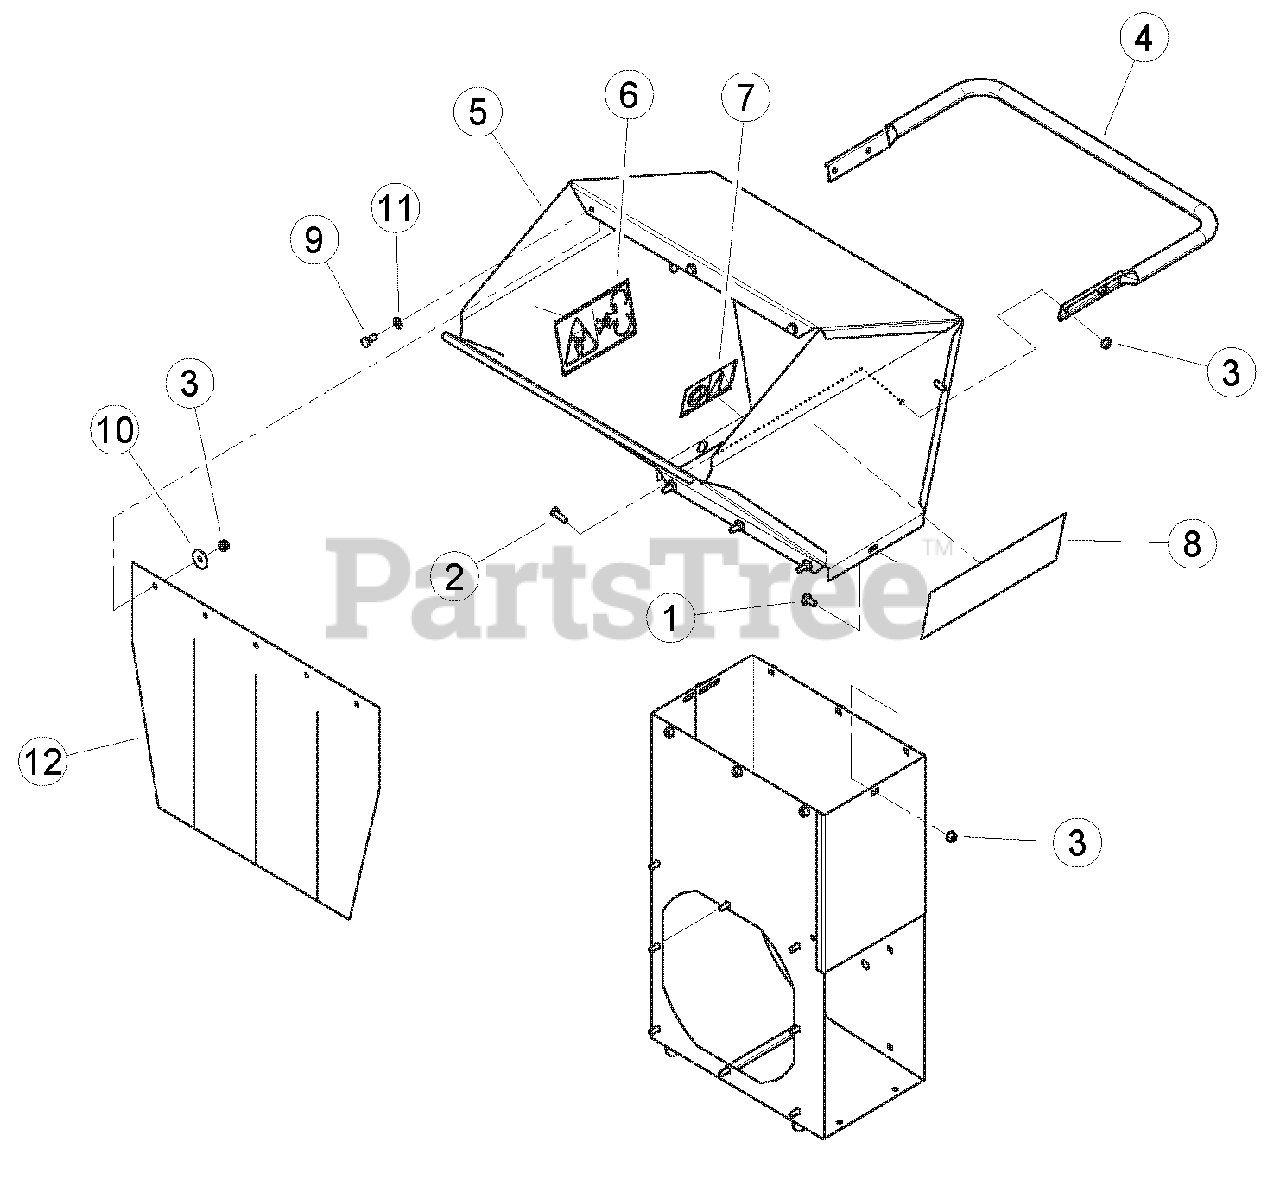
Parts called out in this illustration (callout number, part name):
1	BOLT, 5/16-18 X 3/4 CRG GR5 SN
2	BOLT, 5/16 X 7/8 HEX HD NC GR5 ZP
3	NUT, 5/16 FLANGE TOPLOCK
4	HANDLE, CE COMPLIANT HOPPER
5	ASSEMBLY, EUROPEAN WIDE HOPPER
5	ASSEMBLY, EUROPEAN NAR. HOPPER - SC3206XE ONLY
6	DECAL, BLADE DANGER ISO
7	DECAL, SHREDDER SIZE ISO
8	DECAL, ECHO BEARCAT 12.00 X 4.00
9	BOLT, 5/16 X 3/4 HEX HD GR5 ZP
10	WASHER, 5/16 FENDER ZP
11	WASHER, 5/16 SAE FLAT ZP
12	BELTING, CE COMPLIANT HOPPER
